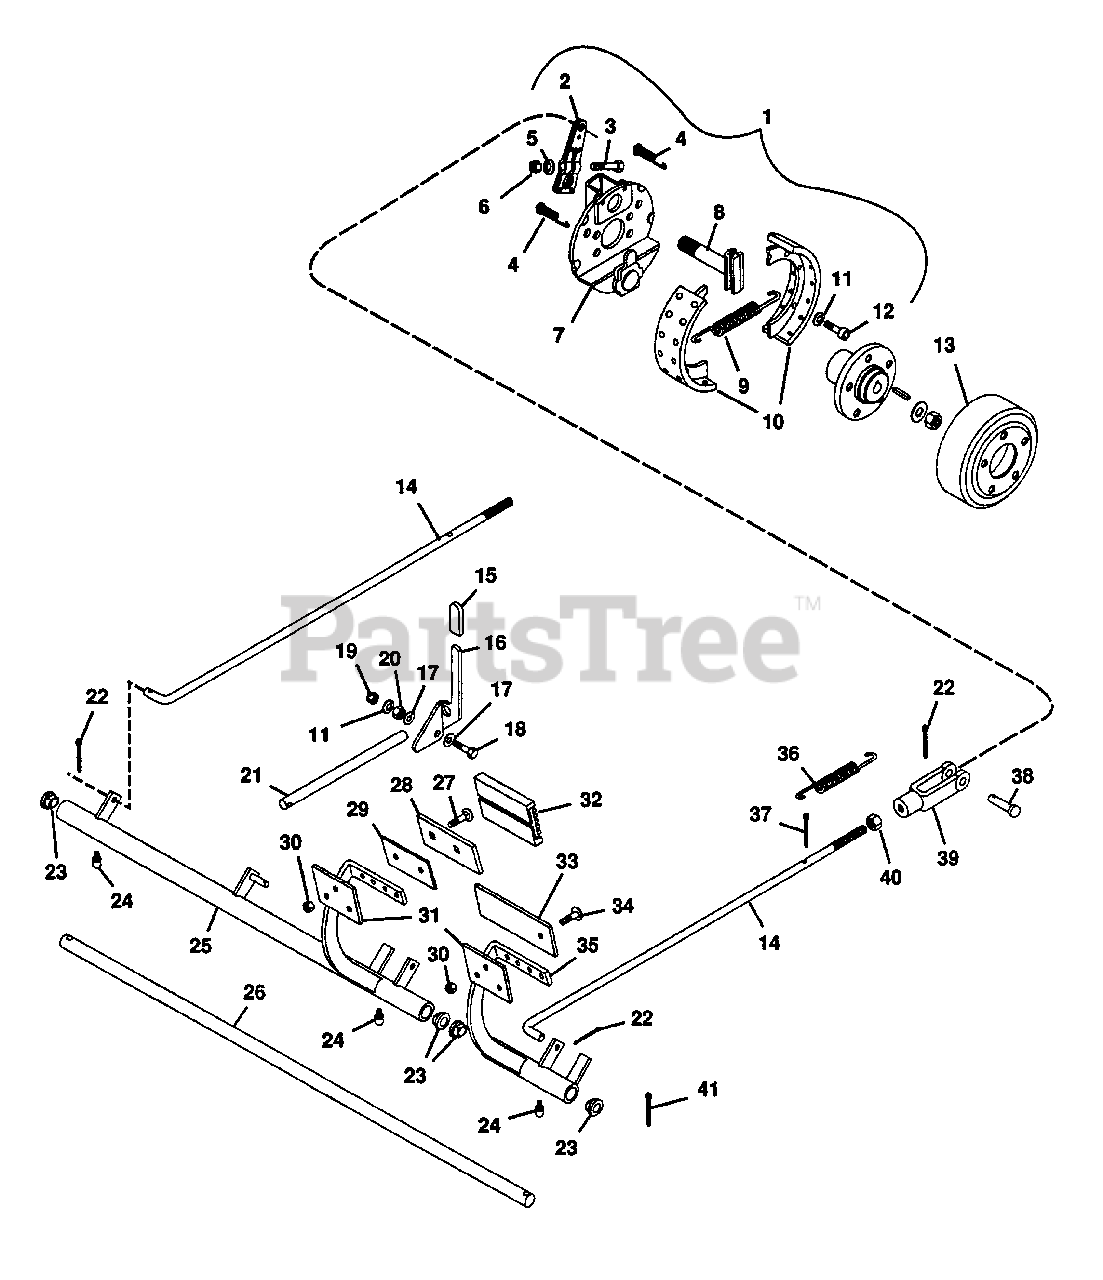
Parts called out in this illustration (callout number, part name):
1	Brake, 7x1.75 Mechanical
2	Arm, Cam Lever
3	Bolt, Hex 5/16-24x1.75
4	Spring, Shoe Retaining
5	Washer, Lock 5/16 Reg.
6	Nut, Hex 5/16-24
7	Plate, Brake
8	Cam, Brake
9	Spring, Shoe Return
10	Shoe, Brake
11	Washer, Lock 3/8 Reg.
12	Screw, Cap HSKT 3/8-16x1.25
13	Drum, Brake
14	Rod, Brake
15	Tips, Brake Lock Lever
16	Arm, Parking Brake Lock
17	Washer, Nylon .375x.75x.060
18	Bolt, Hex 3/8-16x1.375
19	Nut, Lock 3/8-16
20	Nut, Hex 3/8-16
21	Rod, Brake Lock
22	Pin, Cotter .094x.75
23	Bearing
24	Fitting, Lube 1/4-28
25	Weldment, Brake Pedal
26	Shaft, Brake
27	Bolt, Carriage 1/4-20x1.25
28	Pedal, Brake
29	Plate, Brake
30	Nut, Lock 1/4-20
31	Assembly, Brake Lock Plate
32	Pad, Pedal
33	Assembly, Brake Lock Arm
34	Screw, Mach. 1/4-20x1.00
35	Weldment, Brake Pedal
36	Spring, Extension 5.5x.5x20 Rate
37	Pin, Cotter .125x.75
38	Pin, Clevis .375x.948
39	Clevis, 3/8-24 Adjustable
40	Nut, Jam 3/8-24 Hex
41	Pin, Cotter .125x1.25
